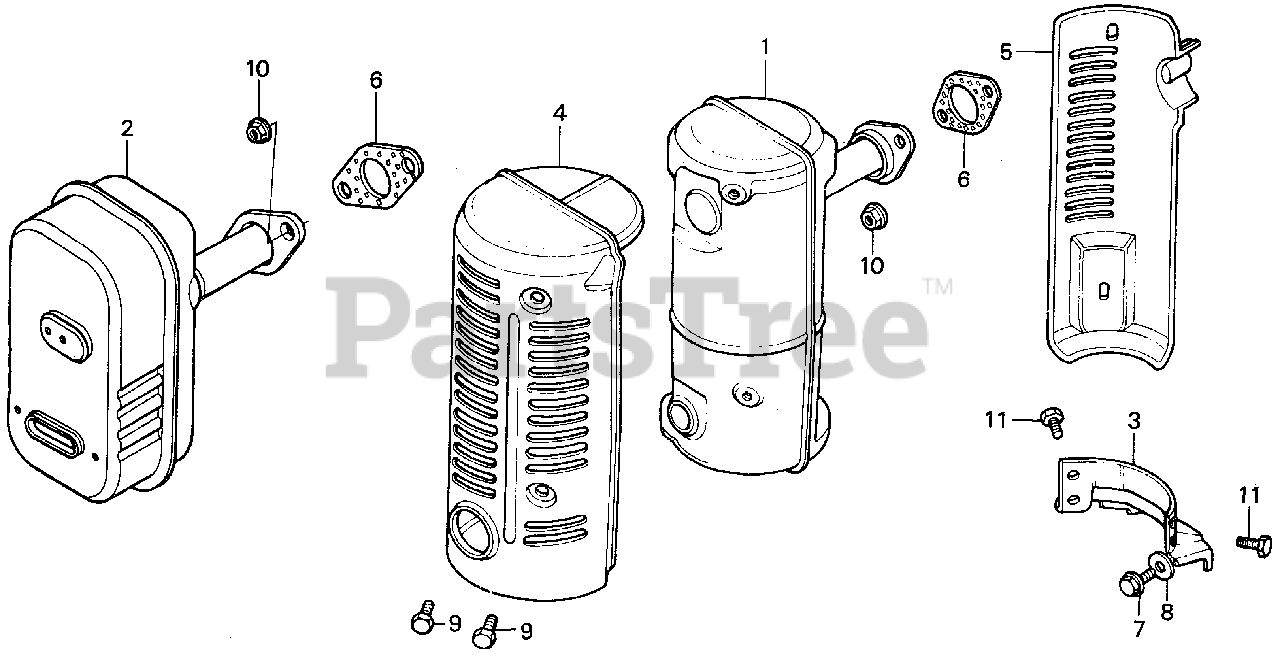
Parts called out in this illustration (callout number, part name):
2	MUFFLER
6	GASKET, MUFFLER
10	NUT, FLANGE (8MM)
